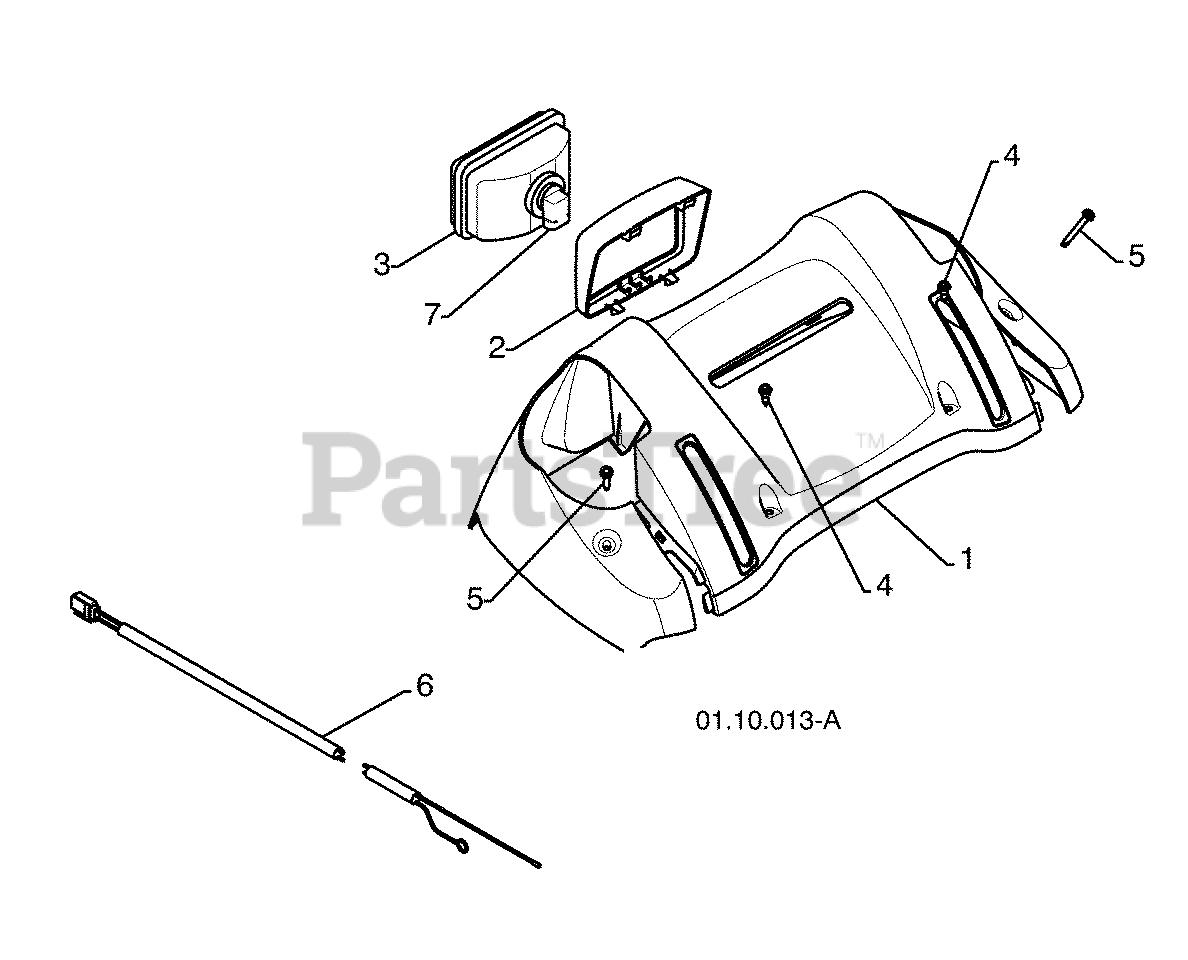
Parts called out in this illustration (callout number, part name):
1	PANEL CONSOLE GRAY
2	HEADLIGHT BEZEL GRAY
3	HALOGEN HEADLIGHT
4	SHOULDER SCREW
5	SCREW 10-24 X 1.25
6	WIRE HARNESS
